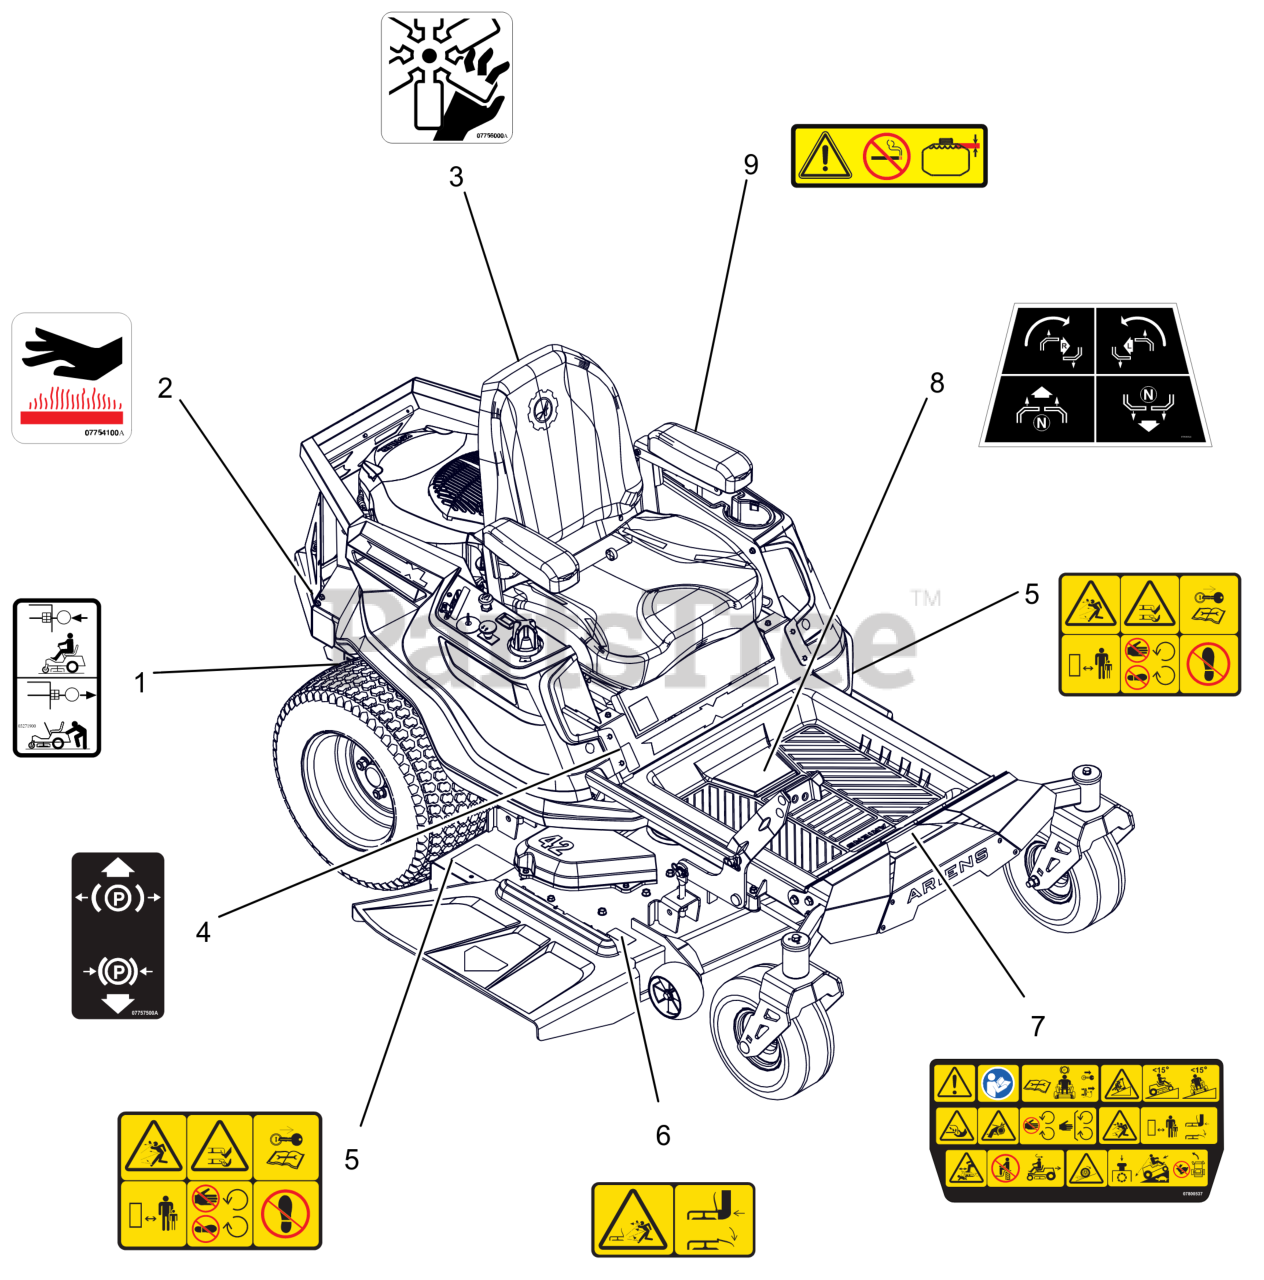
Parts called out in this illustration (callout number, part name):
1	DECAL, TRANSMISSION DISCONNECT
2	DECAL, HOT SURFACE
3	DECAL, DANGER FAN
4	DECAL, PARKING BRAKE LEVER
5	DECAL, SAFETY - MOWER DECK
6	DECAL, SAFETY - DECK GUARDING
7	DECAL, MAIN SAFETY
8	DECAL, STEERING
9	DECAL, FUEL WARNING
